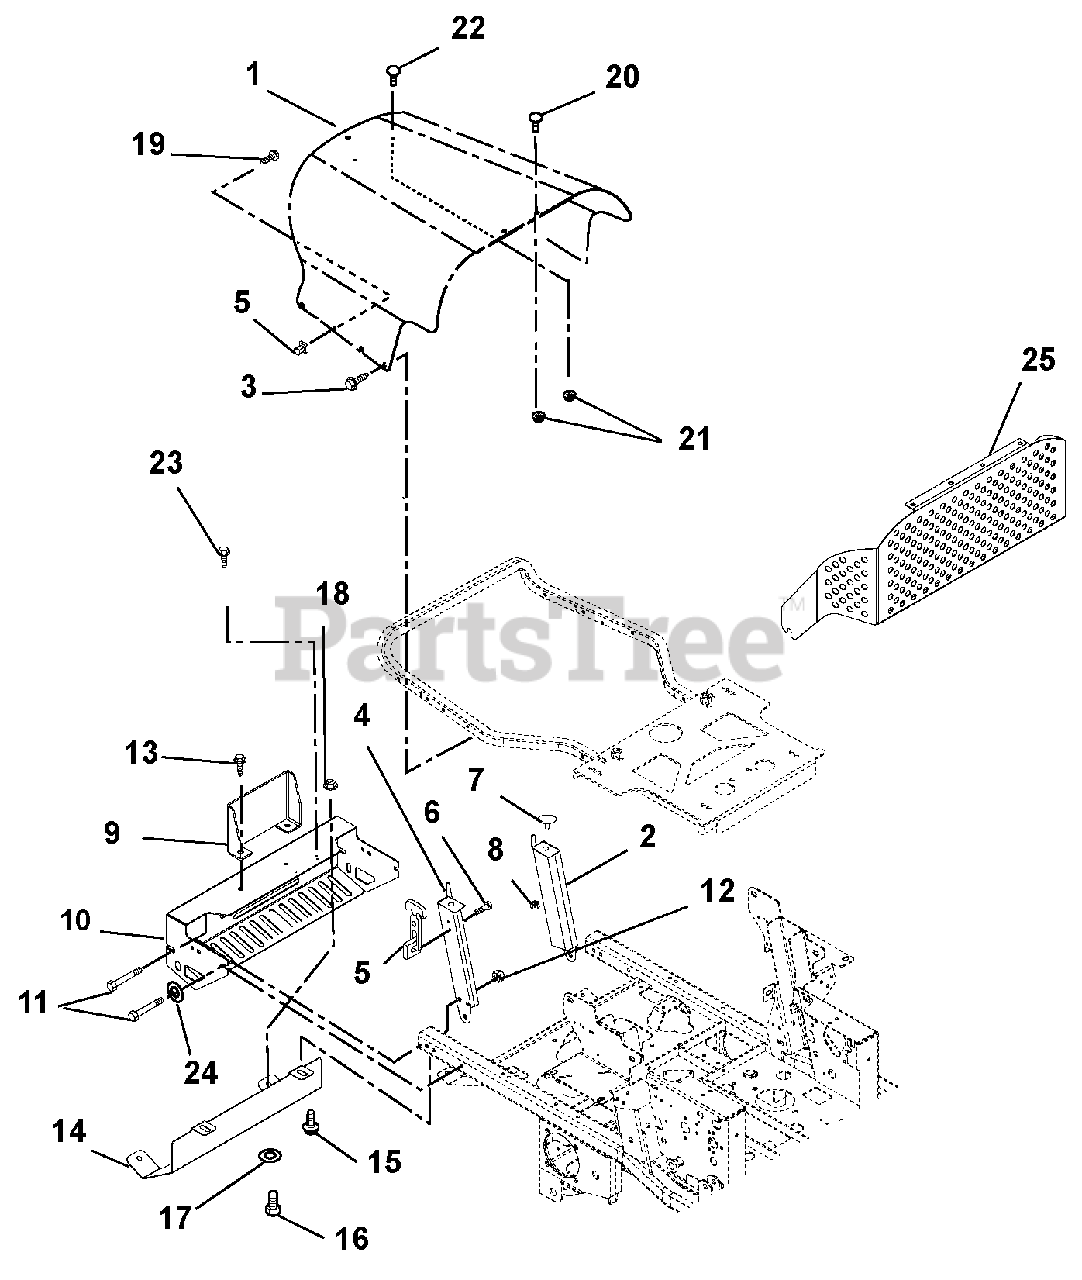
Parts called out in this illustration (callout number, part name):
2	Weldment, Hood Support, Left Hand
3	Screw, Tapping Hex Washer Head .38-16 x .75
4	Weldment, Hood Support Right Hand
5	Latch, Rubber
6	Screw, Machine Hex Washer Head 10-24 x .50
7	Button Bumper
8	Nut, Spin Lock Flange .312-18
9	Guard, Muffler
10	Bumper, Rear
11	Bolt, Hex .38-16 x 2.75 Grade 5
12	Nut, Locking Top Flange .38-16
13	Screw, Tapping Hex Washer Head .38-16 x .75
14	Heat Shield
15	Screw, Tapping Hex Washer Head .38-16 x .50 Thread Rolling YWZ
16	Bolt, Hex .38-16 x .75 Grade 5
17	Washer, Flat Steel .438 x1.00 x .083 YWZ
18	Nut, Locking Top Flange .38-16
19	Screw, Machine Hex Washer Head 10-24 x 1.50
20	Bolt, Round Head Square Neck .25-20 x .50 Grade 5
21	Nut, Locking Top Flange .25-20
22	Bolt, Round Head Square Neck .25-20 x .75 Grade 5
23	Screw, Tapping Hex Washer Head Thread .25-20 x .50
24	Washer, Flat Steel .406 x .812 x .065
25	Plenum, Hood
